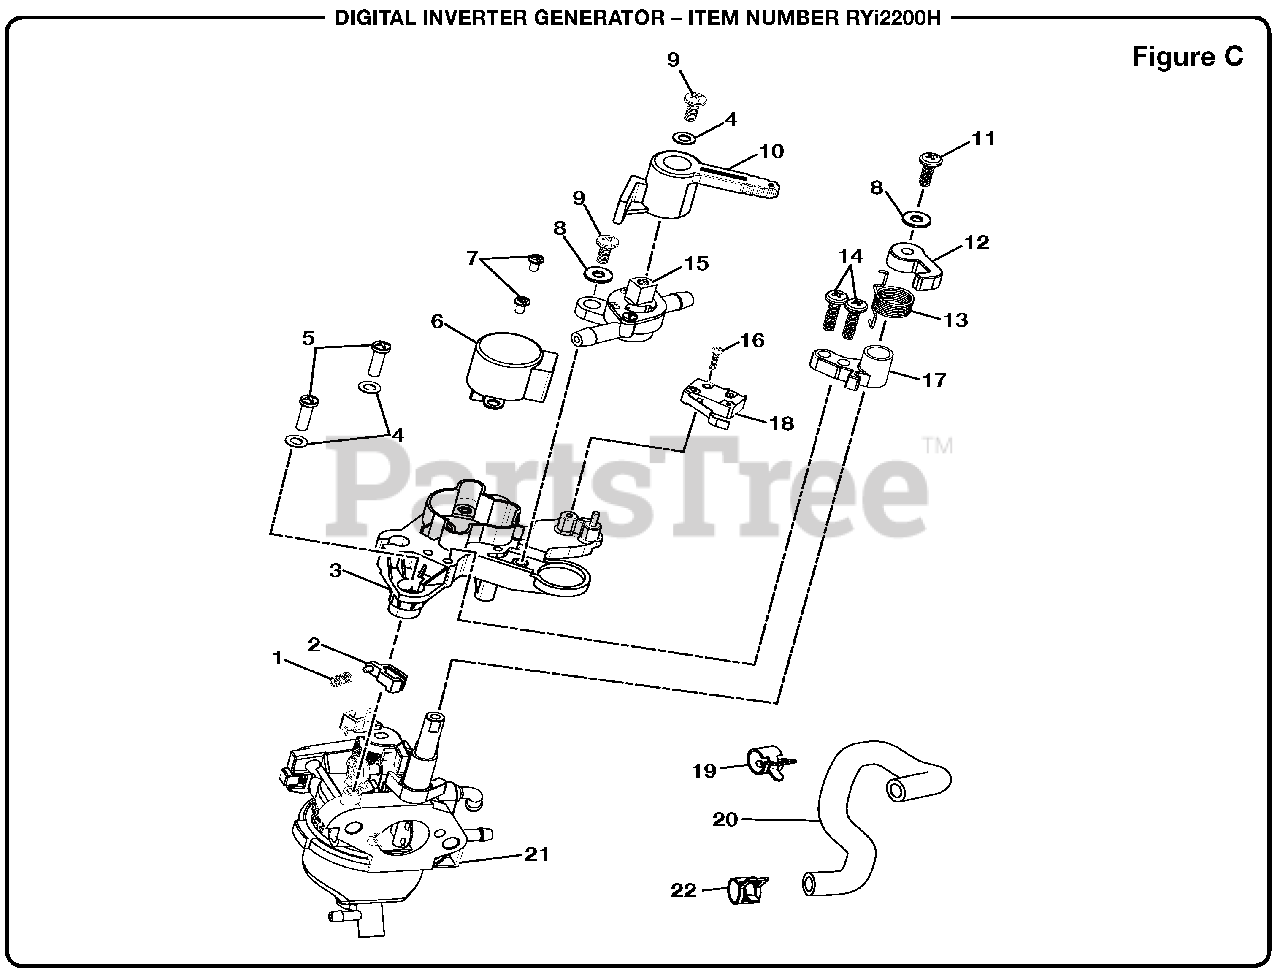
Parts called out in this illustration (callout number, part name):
1	Governor Damping Spring
2	Governor Joint
3	Governor Motor Bottom Housing
4	Spring Washer (ID41 X OD76)
5	Screw (M4 x 14 mm, Phillips Pan Hd)
6	Governor (Stepper Motor)
7	Screw (M3 x 5 mm)
8	Flat Washer (OD10 x ID42 x 1t)
9	Screw (M4 x 10 mm, Phillips Hd)
10	Control Lever
11	Screw (M42 x 12 mm)
12	Choke Lever
13	Torsion Spring
14	Screw (M42 x 16 mm)
15	Fuel Valve
16	Screw (M25 x12 mm, Micro Switch)
17	Support Bracket
18	Stop Switch
19	Hose Clamp (95 mm)
20	Fuel Hose (Fuel Valve To Carburetor)
21	Carburator
22	Hose Clamp (7 mm)
